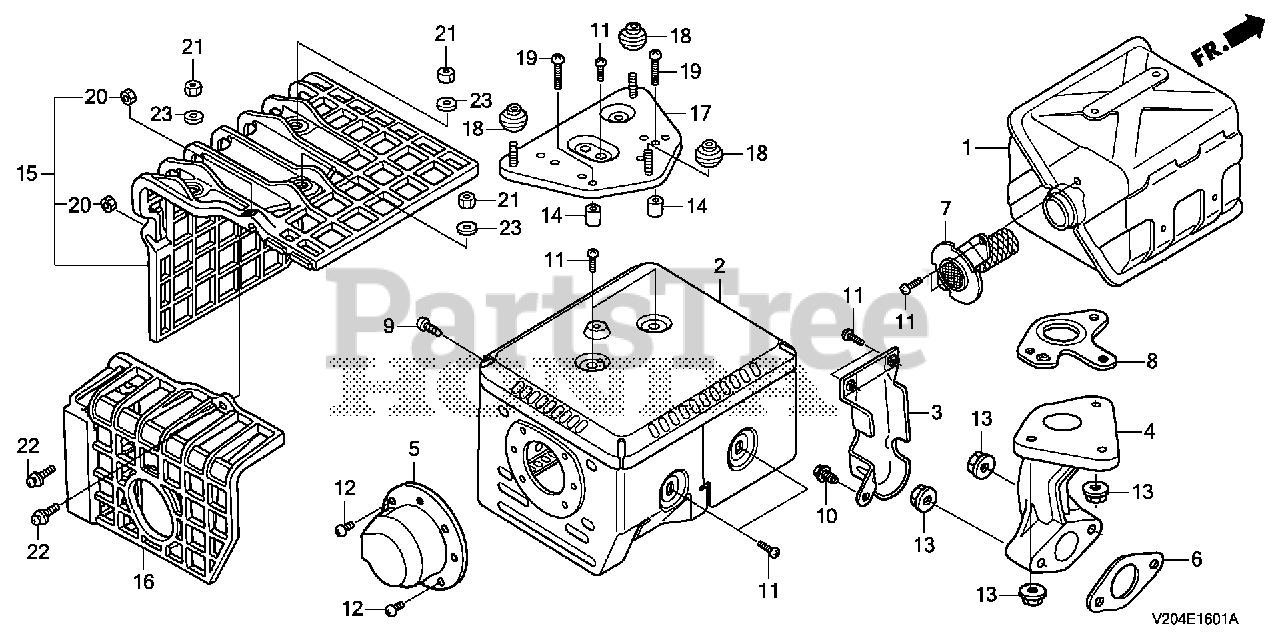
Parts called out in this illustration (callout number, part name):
1	MUFFLER
2	PROTECTOR, MUFFLER
3	PROTECTOR, EX. PIPE
5	CAP, MUFFLER
6	GASKET, EX. PIPE
7	ARRESTER, SPARK
8	GASKET, MUFFLER (ARRESTER)
8	GASKET, MUFFLER (ARRESTER)(THAI LEAKLESS)
9	SCREW, TAPPING (6X10)
10	BOLT, FLANGE (6X12) (CT200)
11	SCREW, TAPPING (5X8)
12	SCREW, TAPPING (4X6) (TO INSTALL OPTIONAL SPARK ARRESTER)
13	NUT, FLANGE (8MM)
14	COLLAR, AIR CLEANER HOUSING
15	COVER, MUFFLER
16	COVER, RR.
18	SPACER, MUFFLER COVER
19	SCREW, TAPPING (5X25)
20	NUT, U (6MM)
21	NUT, HEX. (5MM)
22	SCREW-WASHER (6X20)
23	WASHER, PLAIN (5MM)
